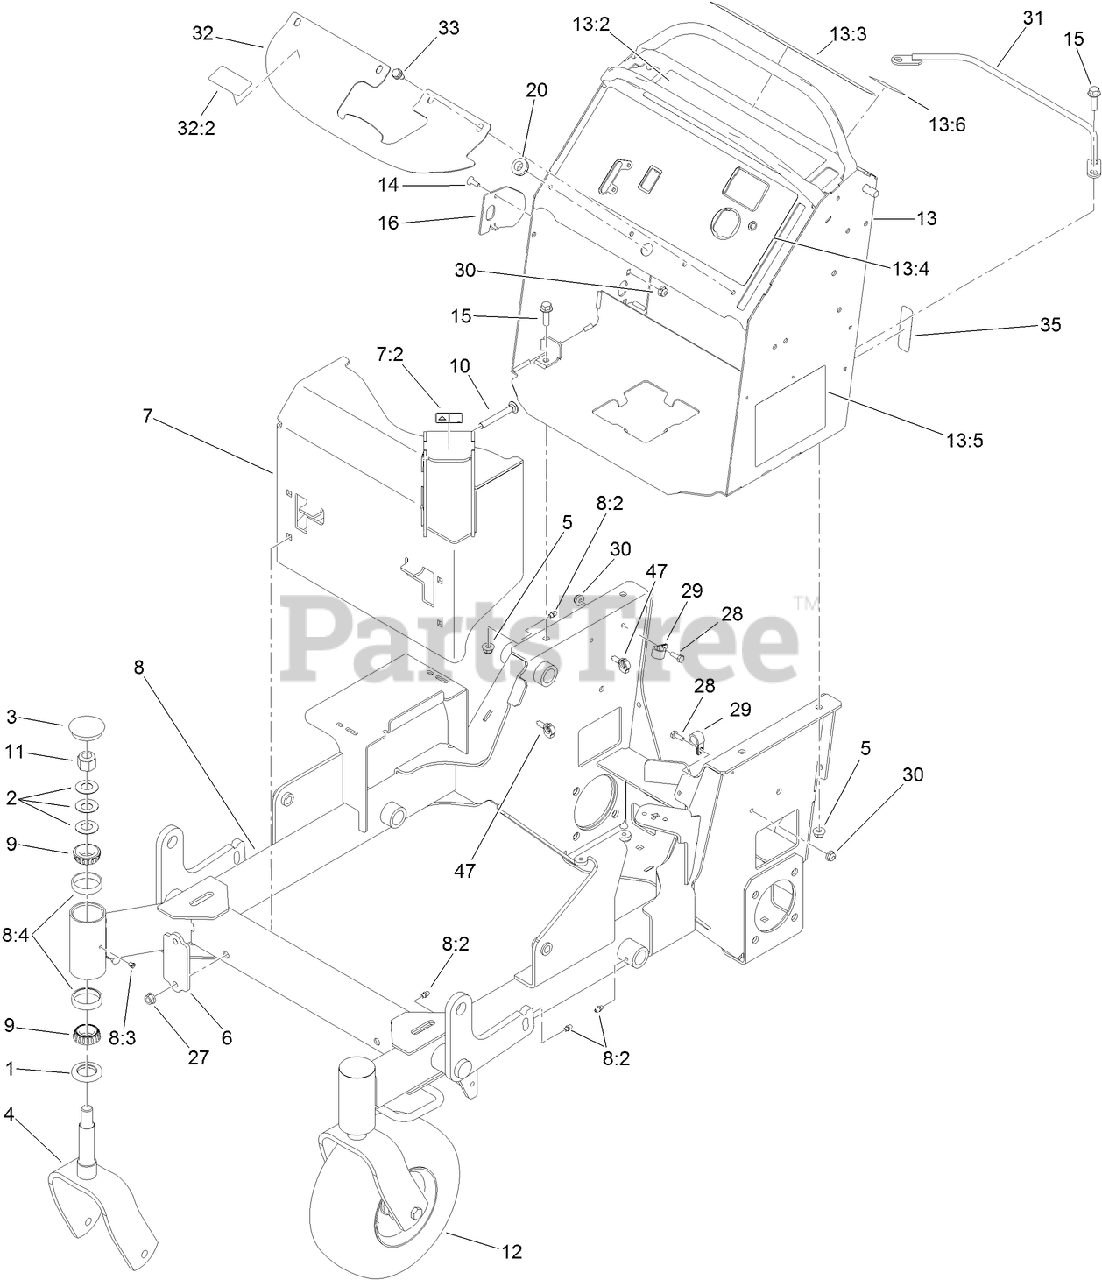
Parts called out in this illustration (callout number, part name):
1	SEAL-GREASE
2	WASHER-BELLVILLE
3	CAP-GREASE
4	FORK-CASTER
5	NUT-HF, NI
6	BRACKET-MOUNTING, GUARD
7	MUFFLER GUARD ASM
7:2	DECAL-WARNING
8	FRAME ASM
8:2	FITTING-GREASE
8:4	CUP-BEARING
9	BEARING-ROLLER, TAPERED
10	SCREW-CARR
11	NUT-LOCK, NI
12	WHEEL/TIRE AND BEARING ASM
13	CONTROL TOWER ASM
13:2	DECAL-OPC
13:3	DECAL-WARNING
13:4	DECAL-PANEL, CONTROL
13:5	DECAL-SERVICE AID
13:6	DECAL-STABILITY, CE
14	BOLT-CARR
15	SCREW-HHF
16	PLATE-STRIKER
20	GROMMET
27	NUT-HF
28	SCREW-HH
29	CLAMP-CABLE
30	NUT-HF
31	RETAINER-CABLE
32	COVER-TANK
32:2	DECAL-FILL, FUEL
33	SCREW-HWHTF
35	DECAL-FUSE
47	CLIP-HARNESS
